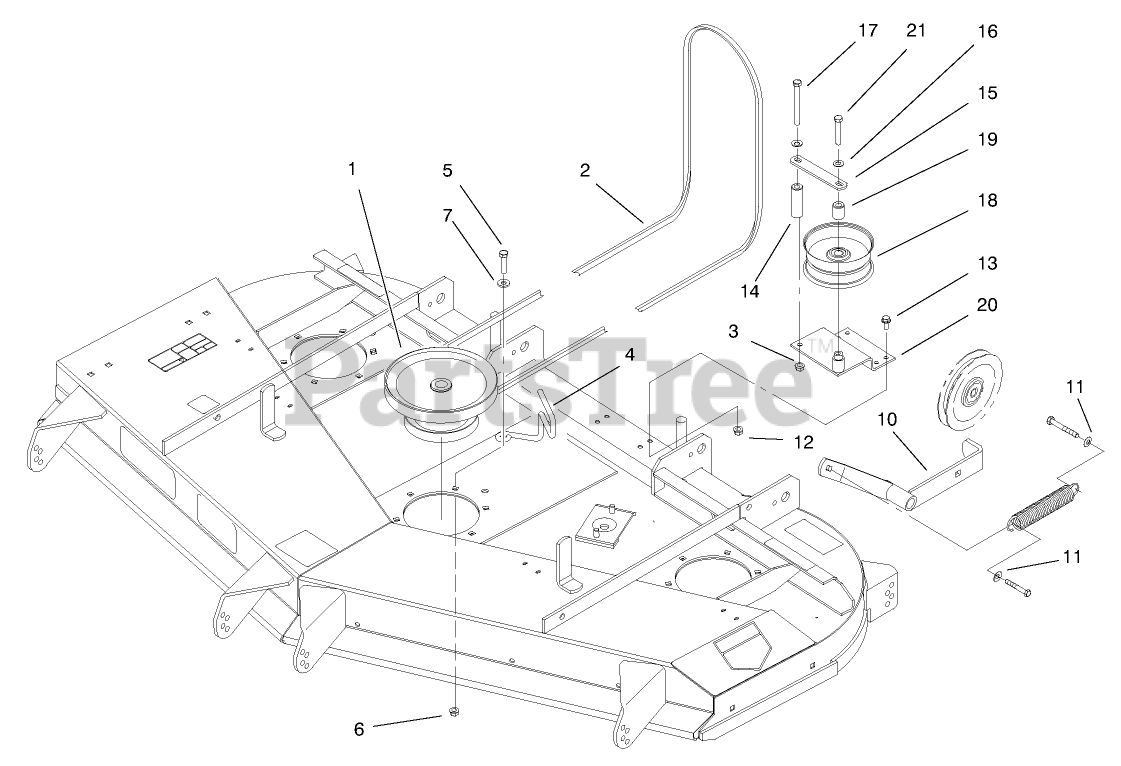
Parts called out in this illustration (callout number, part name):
1	PULLEY AND HUB ASM
2	V-BELT-DRIVE, DECK
3	NUT-HHF, WHIZ
4	GUIDE-BELT
5	SCREW-HH
6	NUT-HF
7	WASHER-FLAT
10	IDLER ARM ASM
11	WASHER-FLAT
12	NUT-HF
13	SCREW-HHF
14	SPACER-BRACKET
15	Plate-Guide Belt
16	Washer
17	SCREW-HH
18	Pulley
19	Spacer
20	BRACKET-PULLEY
21	SCREW-HH
